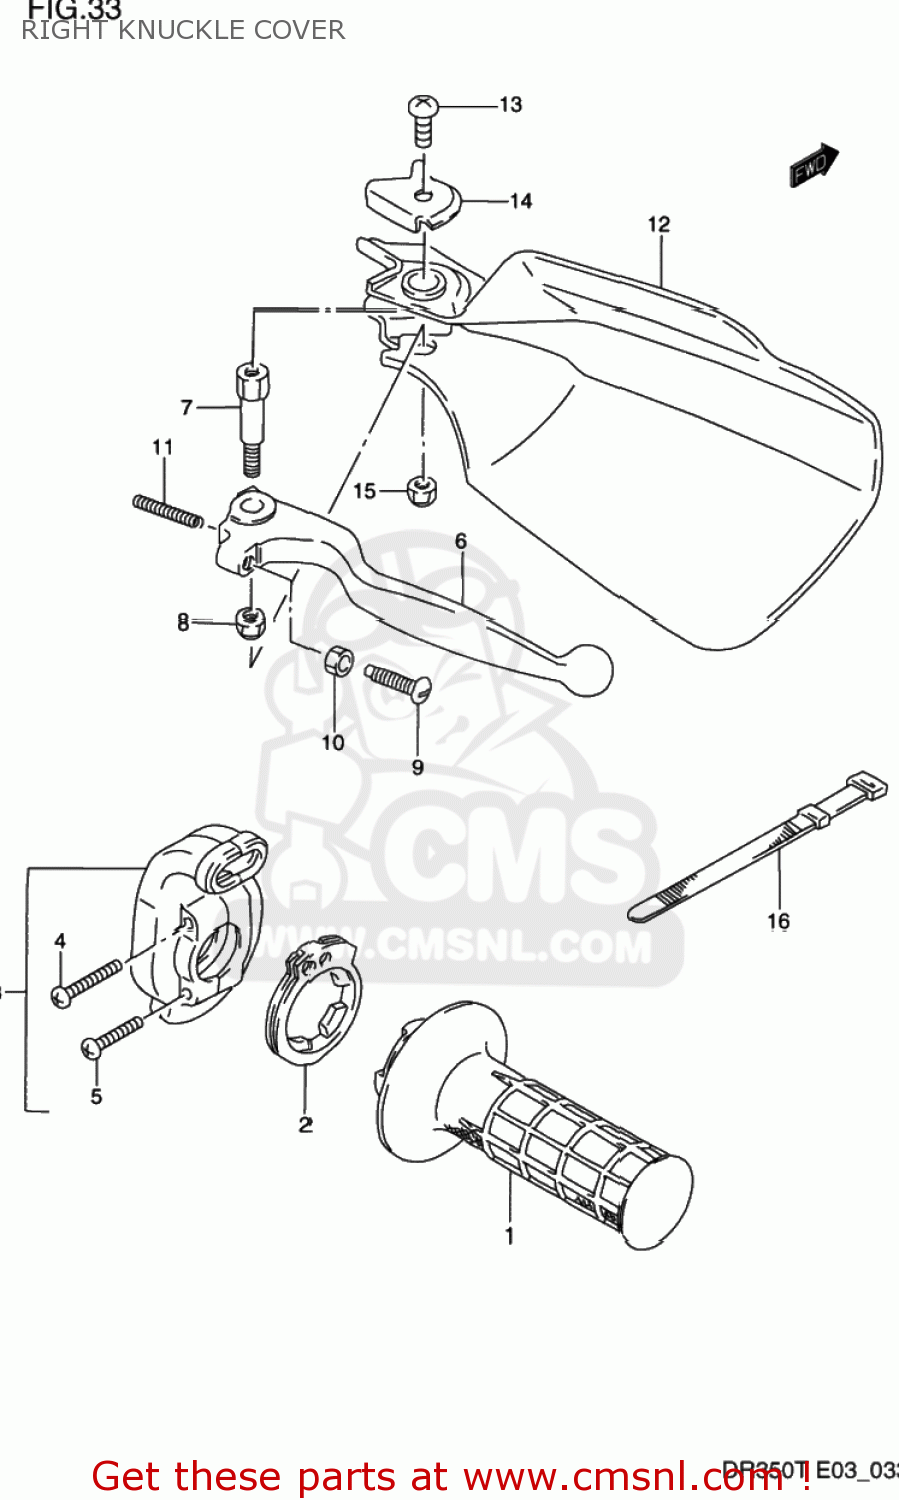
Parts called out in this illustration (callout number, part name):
1	GRIP,THROTTLE
2	ROTOR,THROTTLE GRIP
3	CASE ASSY,THROTTLE
4	SCREW(5X25)
5	SCREW 5X20
6	LEVER,BRAKE
7	BOLT,BRAKE LEVER PIVOT
8	NUT 6MM
9	BOLT,ADJUST
10	NUT ,5MM
11	SPRING,RETURN
12	COVER,KNUCKLE,R
13	SCREW
14	PLATE,KNUCKLE COVER,R UPR
15	NUT 6MM
16	CLAMP(L:120)
